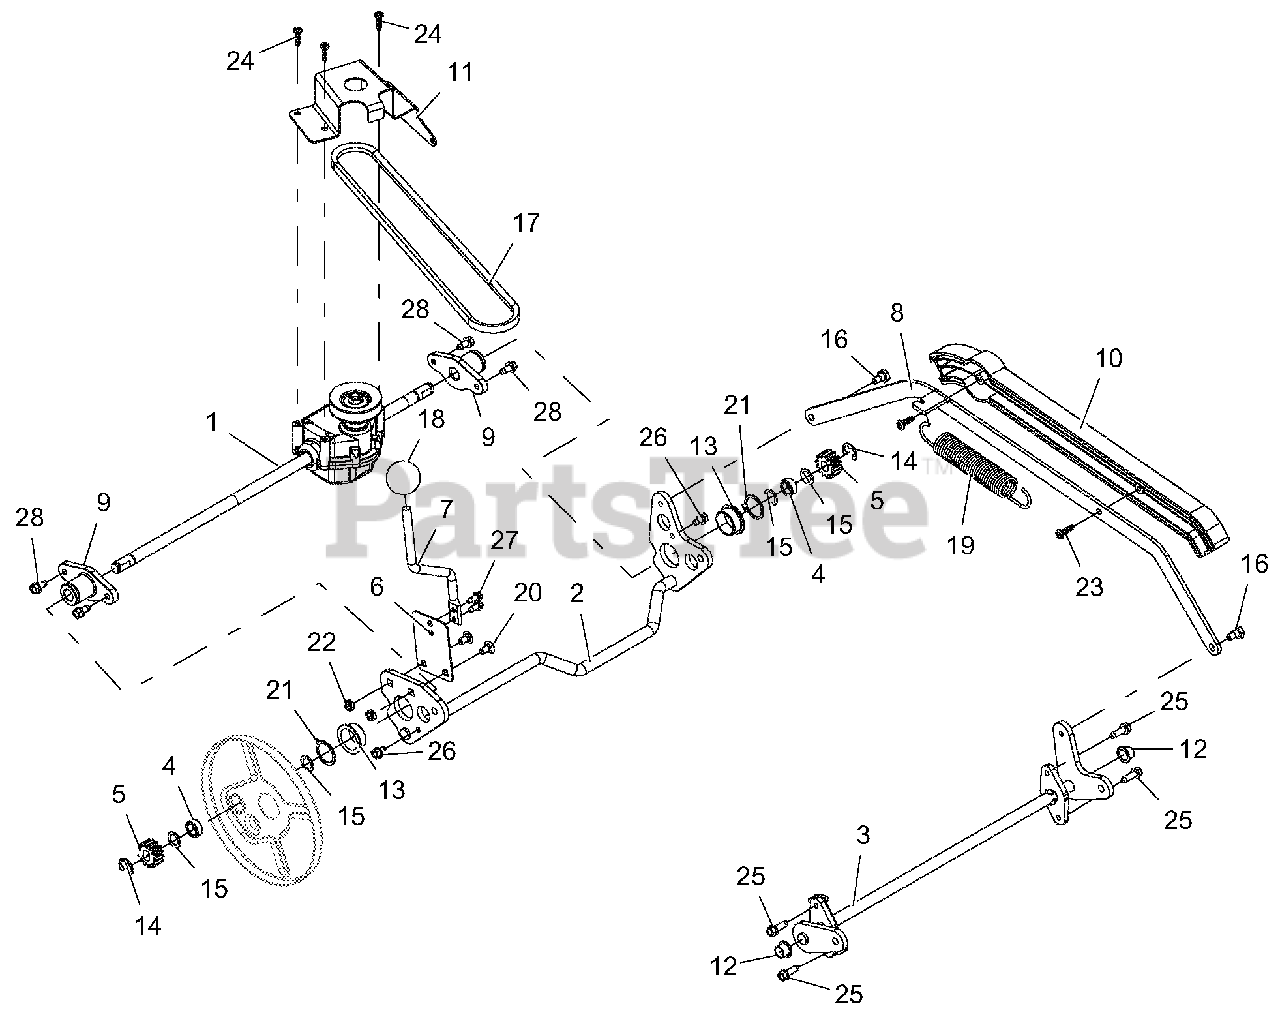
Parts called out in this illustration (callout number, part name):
1	TRANSAXLE, AUTOMATIC, LM, 9:1
2	WLDMT, LM REAR AXLE
3	WLDMT, LM FRONT AXLE
4	SPCR, PM .500ID x .75OD x .321
5	GEAR, PINION , LM WHEEL DRIVE
6	PLATE, HOC SPRING
7	LEVER, HOC ADJUST
8	LINK, HOC CONNECT
9	HUB, LM REAR AXLE
10	COVER, LINK ROD
11	GUIDE, BELT TRANSMISSION
12	BUSHING, POLYLINER - .50 SPLI T
13	BSHG, FLANGE 1.0 x 1.125 x .50 x 1.375
14	RG-RTNG-EXT .500 x .042 (E)
15	WASHER-FLAT-STL, .500 x .750 x .020
16	BOLT, SHLDR .320 x .210 x .25-20 SELF-TAPPING
18	KNOB, BALL - BLACK 1.47" .375-16
19	SPRG, EXTENSION
20	BLT-RDHDSQNK .25-20 x .50 G5 Y
21	RG-RTNG-EXT 1.00 x .042
22	@NUT-LK-CTR-JAM .25-20 YWZC
23	SCR-TAP #12-14 x .75 PLASTITE BLZC
24	SCR-TAP #10-14 x .75 PLASTITE BLZC
25	SCR-TAP .25-20 x .75 HWH TR YWZ
27	SCR-TAP 12-24 x .50 HWH TR YWZC
28	SCR-TAP .25-20 x .50 HWH TR YWZ
